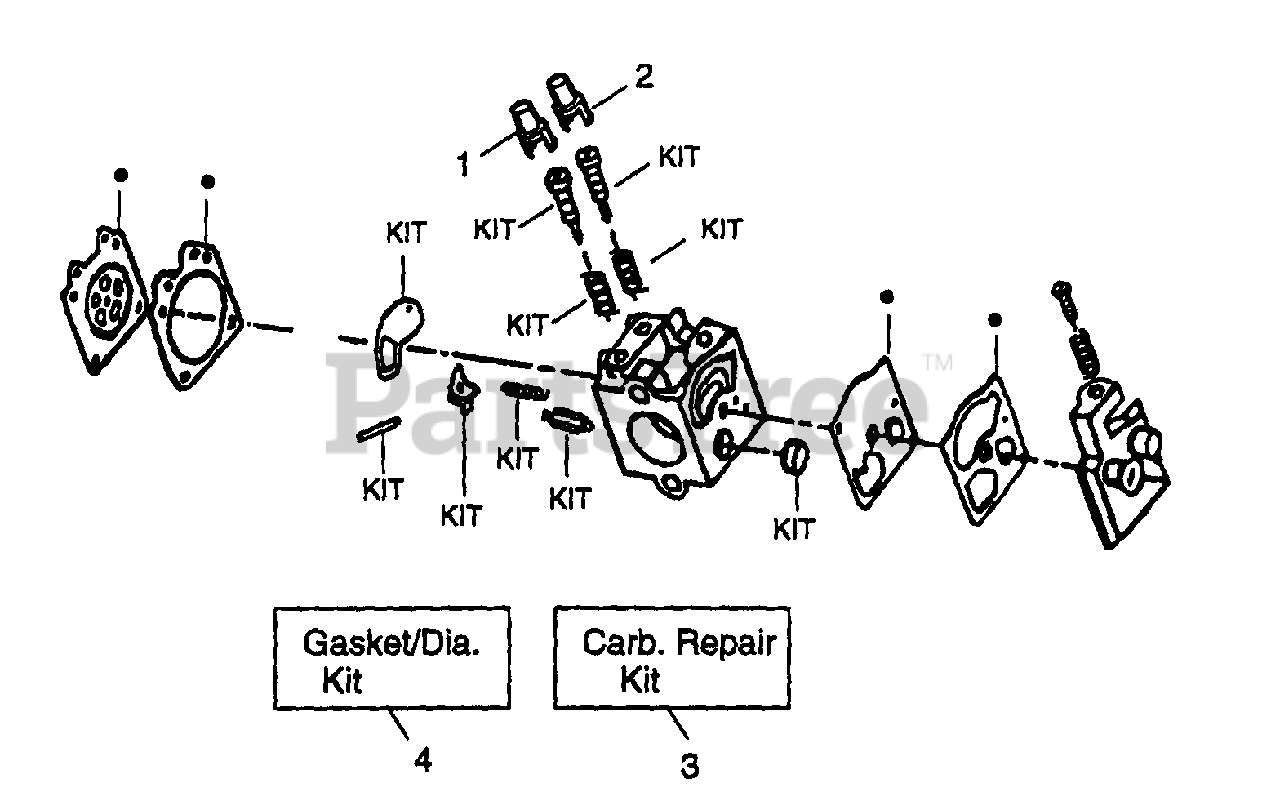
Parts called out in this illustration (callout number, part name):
1	Limiter Cap-Low
2	Limiter Cap-High
3	Carburetor Repair Kit
4	Gasket/Diaphragm Kit
